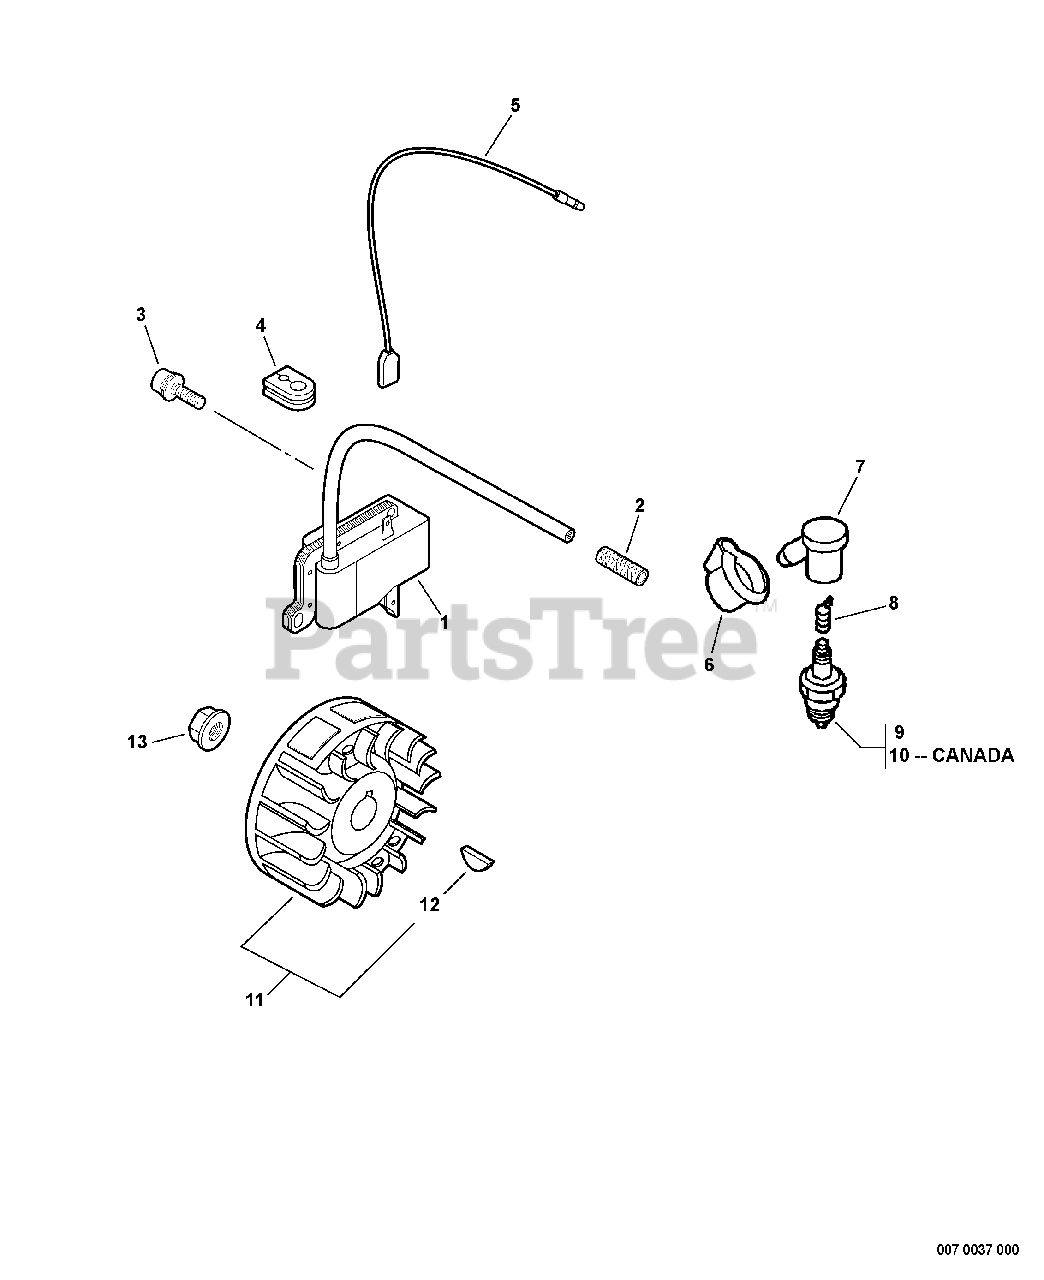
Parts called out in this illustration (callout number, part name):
1	COIL, IGNITION
2	TUBE, INSULATOR
3	SCREW - 5X20
5	LEAD - IGNITION
6	COVER, DUST
7	CAP, SPARK PLUG
8	TERMINAL, SPARK PLUG CAP
9	SPARK PLUG -- BPM-7A
10	SPARK PLUG -- RCJ-6Y
11	FLYWHEEL KIT
12	KEY - 3X14
13	NUT - 10 -- FLANGE
